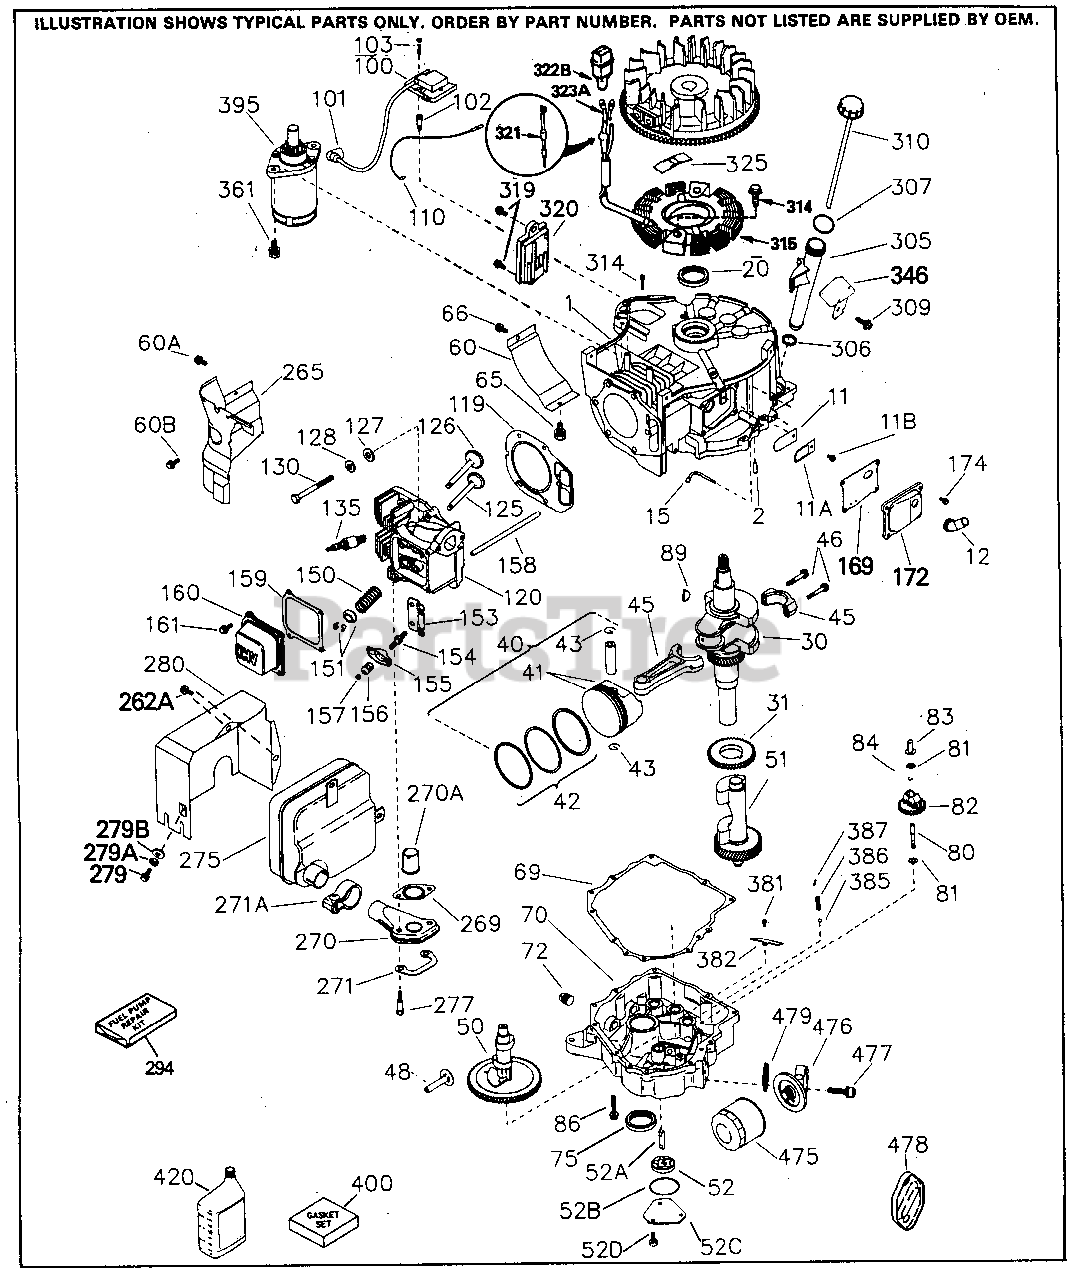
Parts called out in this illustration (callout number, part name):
1	"Cylinder (Incl. 2, 11B, 20 & 72B)
2	Dowel Pin
11	Check Valve
11A	Breather Plate
15	Governor Rod (1/4" dia.)
20	Oil Seal
28	Lock Nut, 8-32
30	Crankshaft
31	Counterbalance Gear
40	Piston, Pin & Ring Set (Std.)
40	Piston, Pin & Ring Set (.010" OS)
40	Piston, Pin & Ring Set (.020" OS)
41	Piston & Pin Ass'y. (Std.) (Incl. 43)
41	Piston & Pin Ass'y. (.010" OS) Incl. 43
41	Piston & Pin Ass'y. (.020" OS) Incl. 43
42	Ring Set (Std.)
42	Ring Set (.010" OS)
42	Ring Set (.020" OS)
43	Piston Pin Retaining Ring
45	Connecting Rod (Incl. 46)
45	Connecting Rod Ass'y. (.010" US) Incl . 46
45	Connecting Rod Ass'y. (.020" US) Incl . 46
46	Connecting Rod Bolt
48	Valve Lifter
50	Camshaft (MCR)
50A	Camshaft Repair Kit
51	Counterbalance Weight
51A	Counterbalance Weight
52	Oil Pump Assembly
52A	Oil Pump Shaft
52B	* "O" Ring
52C	Oil Pump Cover (Incl. 52B)
52D	Screw, T-30, 1/4-20 x 43/64"
60	Air Baffle
60B	Screw, 10-24 x 1/2"
69	* Mounting Flange Gasket
70	Mounting Flange (Incl. 72, 72A, 75, 8 0, 381 thru 387) 387)
72A	Oil Drain Plug (3/8-18)
72B	Oil Drain Plug
75	Oil Seal
75A	Oil Seal (Governor Shaft)
80	Governor Shaft
81	Washer
82	Governor Gear & Weight Assy
83	Governor Spool
84	Retaining Ring
86	Screw, 1/4-20 x 1-15/32"
89	Flywheel Key
90	Flywheel
91	Flywheel Fan
91A	Flywheel Fan Retainer
100	Solid State Ignition (Incl. 101)
101	Spark Plug Cover
102	Solid State Mounting Stud
103	Screw, T-15, 10-24 x 15/16"
110	Ground Wire
110A	Fuel Solenoid Wire - Green, 9.0''
119	* Cylinder Head Gasket
120	Cylinder Head (Incl. 119, 151A, 207A)
125	Exhaust Valve (Std.)
125	Exhaust Valve (1/32" OS)
126	Intake Valve (Std.)
128	Belleville Washer
130	Screw, 5/16-18 x 2-45/64"
130A	Screw, 5-16/18 x 17/32"
130B	Screw, 1/4-20 x 1/2"
135	Resistor Spark Plug (RN4C) also avail able in Packaged Part #740069
150	Valve Spring
151	Valve Spring Keeper
151A	Intake Valve Seal
153	Push Rod Guide
154	Rocker Arm Stud
155	Rocker Arm
156	Rocker Arm Bearing
157A	Jam Nut 5/16-24
158	Push Rod
159	* Rocker Arm Cover Gasket
160	Rocker Arm Housing
161	Screw, T-30, 1/4-20 x 1/2"
169	* Breather Gasket
172	Valve Cover
173	Breather Tube
234	Nut & Lock Washer, 1/4-20
243	Screw, 10-32 x 7/16"
245A	Poly Pre-Filter (also available in Pa ckaged Part #740055B)
265	Cylinder Head Cover
269	* Exhaust Gasket
270A	Exhaust Port Liner
271	Locking Plate (Manifold)
305	Oil Fill Tube
306	* "O" Ring
307	"O" Ring
309	Screw, 1/4-20 x 57/64"
310	Dipstick
315	Alternator Coil (3/5 Split) Incl. 321 -323
322	Connector Body
323	Terminal
325	Wire Clip
325B	Wire Clip
330	Wire Harness
346	Fuel Pump Bracket
361	Screw, 5/16-18 x 29/32"
365	Screw, 8-32 x 27/64"
382	Oil Strainer Screen
386	Pressure Relief Spring
387	Cotter Pin
395	Electric Starter Motor
400	Gasket Set n notes)
406B	Fuel Solenoid Wire Assy.
420	SAE 30 4-Cycle Engine Oil (Quart)
477	Screw, T-30, 5/16-18 x 7/8"
478	Oil Passage Cover (Incl. 479)
479	* Oil Passage Gasket
485	Oil Filter Adapter Kit (Incl. 475,476 & 477) (Optional)
